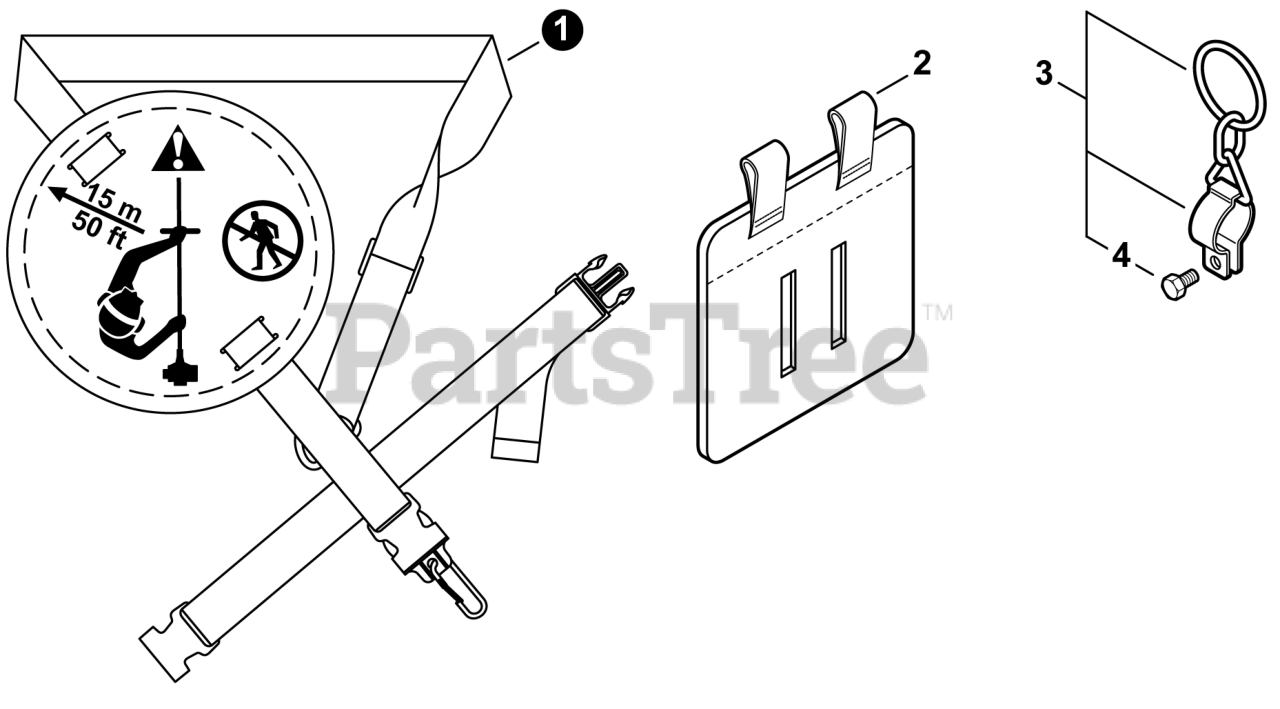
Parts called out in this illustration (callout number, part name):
1	HARNESS, SHOULDER
2	PAD, HIP
3	HANGER SET, HARNESS
4	BOLT, TORX 5×12
